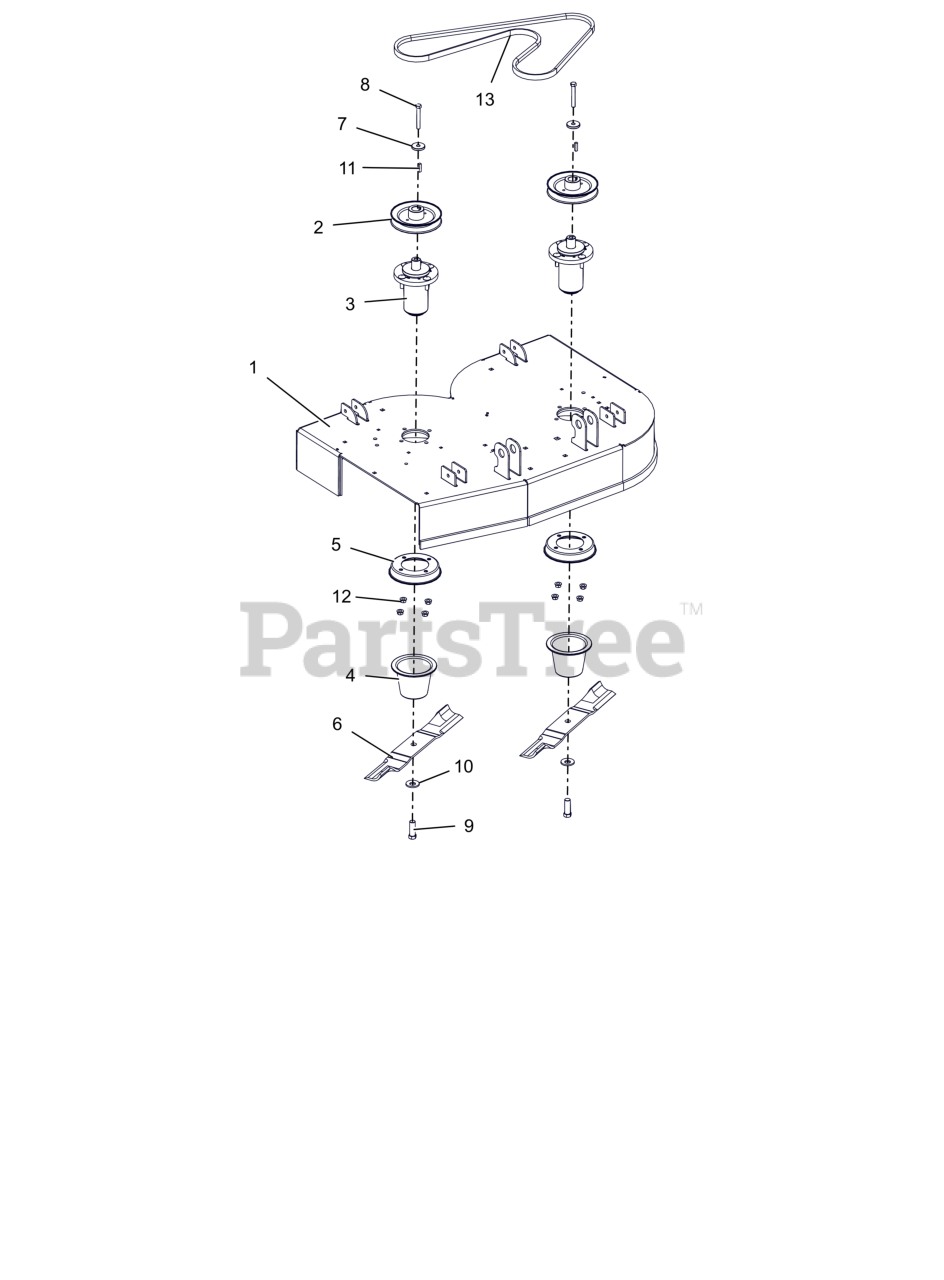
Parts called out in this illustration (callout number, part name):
1	KIT, SVC 36" DECK W DECALS
2	PULLEY, V-1.00 ID X 5.75 OD (BLACK)
3	ASM, MAINT FREE ALUM SPINDLE
4	GUARD, SPINDLE LOWER
5	GUARD, SPINDLE TOP
6	BLADE, 18.00" MOWER (HI-LIFT)
7	RETAINER, SHEAVE
8	BLT, HEX .38-16X2.75 G8 ZCC
9	BLT, HEX .62-18X1.75 G8 ZCC
10	WSHR-BLVL .669X1.535X.138
11	KEY, SQ .25X.25X1.00 RC 40-50
12	NUT-LK-CTR-FLG .375-16 GF ZCC
13	V-BELT, 5L RAW EDGE EPDM
